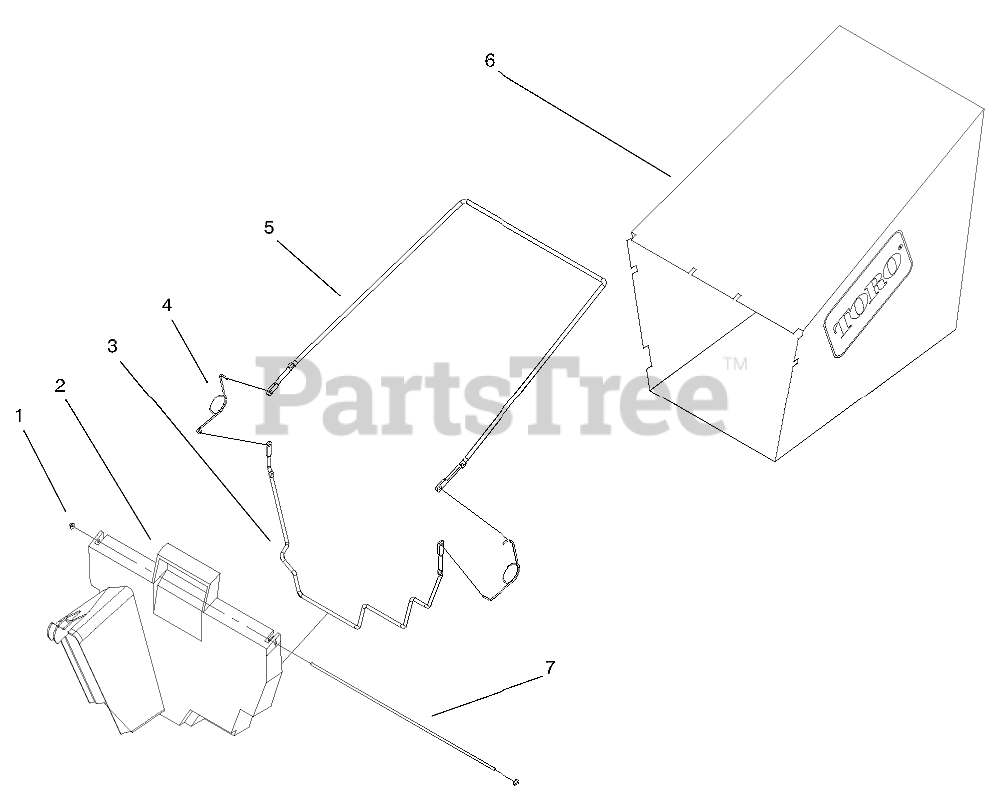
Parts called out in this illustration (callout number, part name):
1	NUT-PUSH
2	DOOR-BAG
3	FRAME-BAG
4	SPRING
5	FRAME-BAG, UPPER
6	BAG-GRASS
7	HINGE-DOOR, BAG
